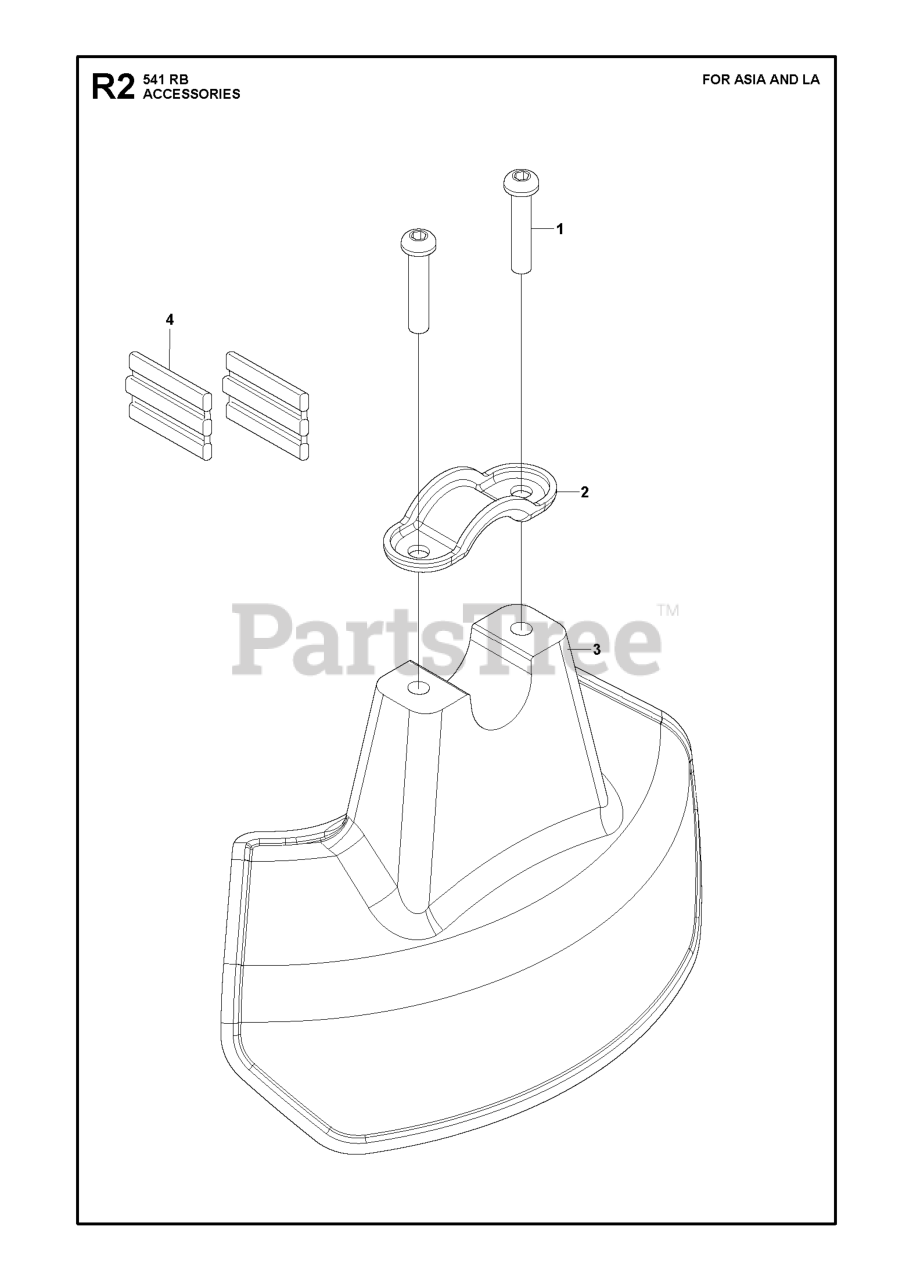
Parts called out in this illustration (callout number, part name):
1	BOLT
2	CLAMP
4	BAR GUARD
